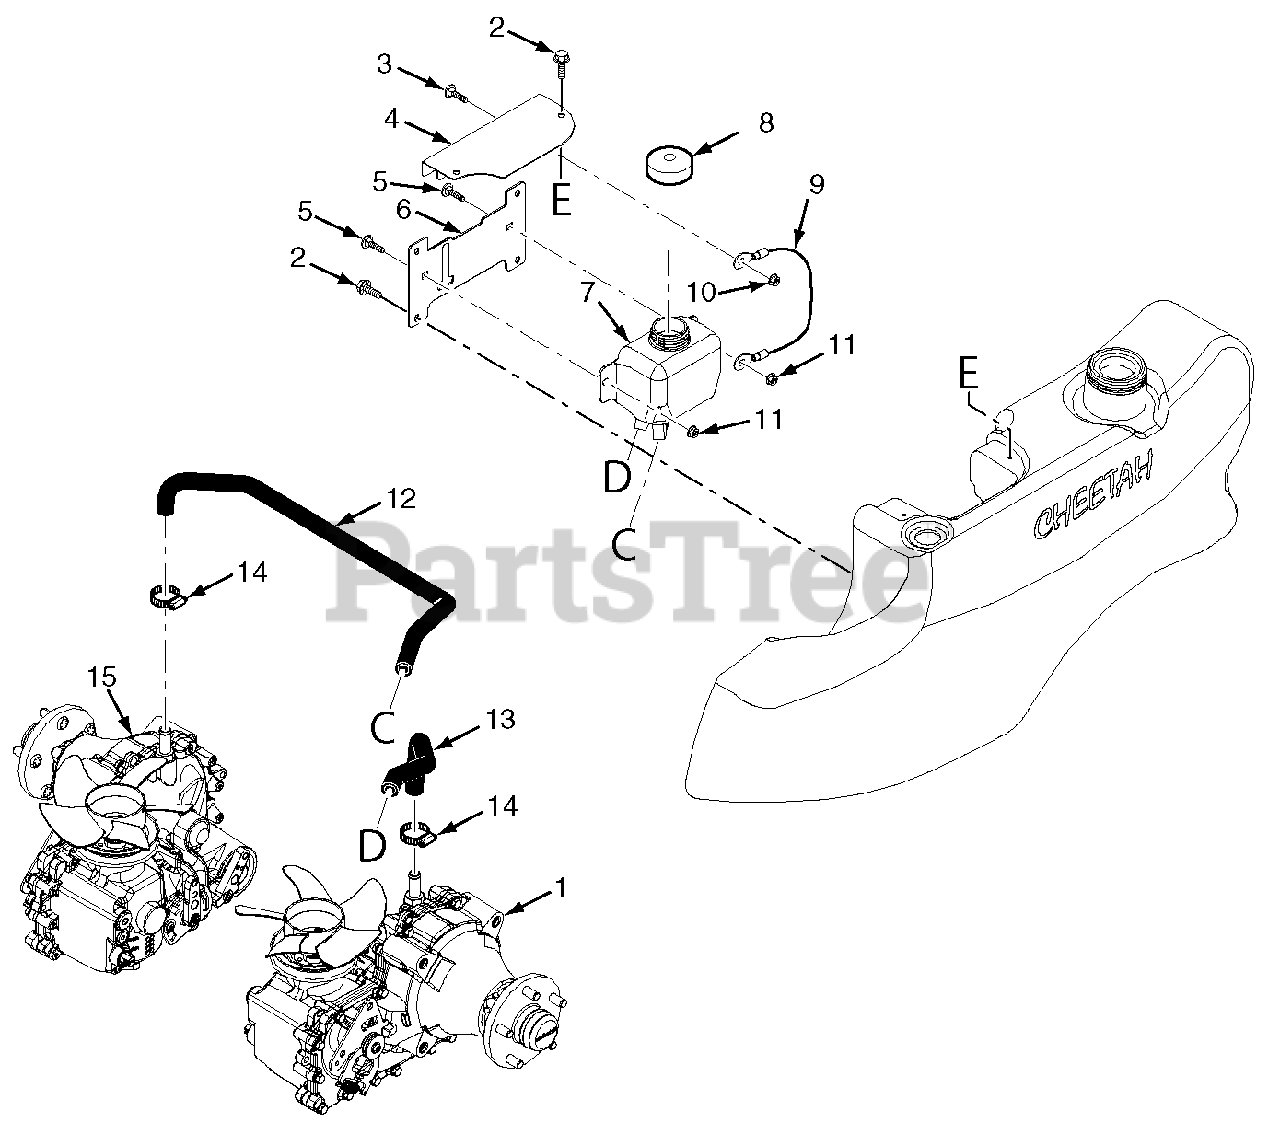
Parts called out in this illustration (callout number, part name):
1	Transaxle, LH
2	Bolt, Hex Head 1/4-20 X 1/2" Serrated Flange
3	Bolt, Carriage 1/4-20 x 3/4"
4	Cover, Oil Reservoir
5	Bolt, Carriage 5/16-18 x 3/4"
6	Plate, Hydro Tank Mount
7	Hydraulic Tank Assembly
8	Cap, Hydraulic Tank
9	Lanyard, Hydraulic Tank
10	Nut, Elastic Stop 1/4-20
11	Nut, FLG HH Elastic Stop 5/16-18
12	Hose, RH Transaxle
13	Hose, LH Transaxle
14	Clamp, 1" Max Dia.
15	Transaxle, RH
